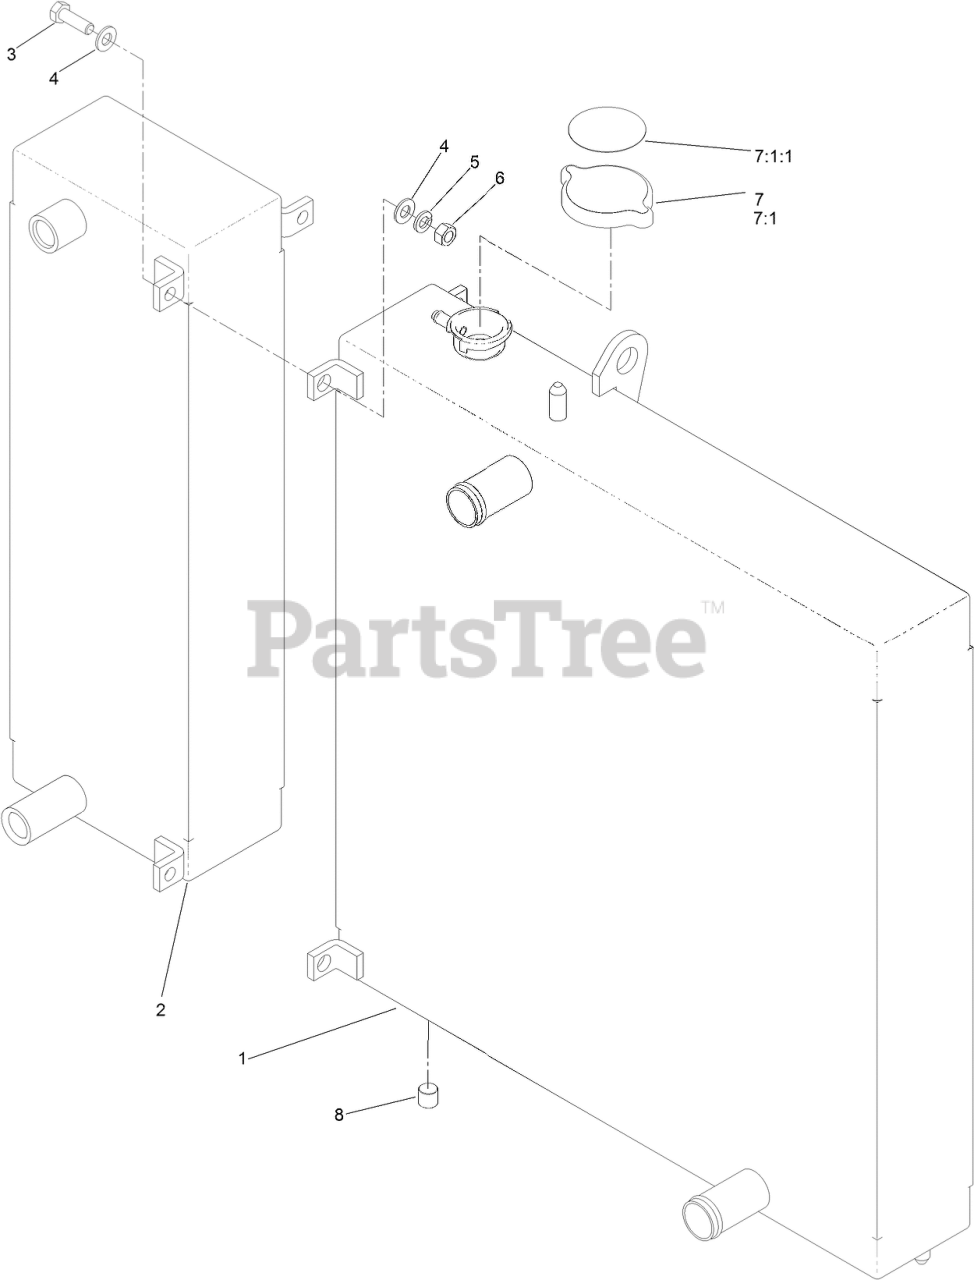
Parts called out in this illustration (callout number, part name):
1	RADIATOR
2	OIL COOLER
3	SCREW-HH
4	WASHER-PLAIN
5	WASHER-LOCK
6	NUT-HEX
7	RADIATOR CAP ASM
7:1	CAP-RADIATOR
7:1:1	DECAL-DANGER
8	PLUG-PIPE
